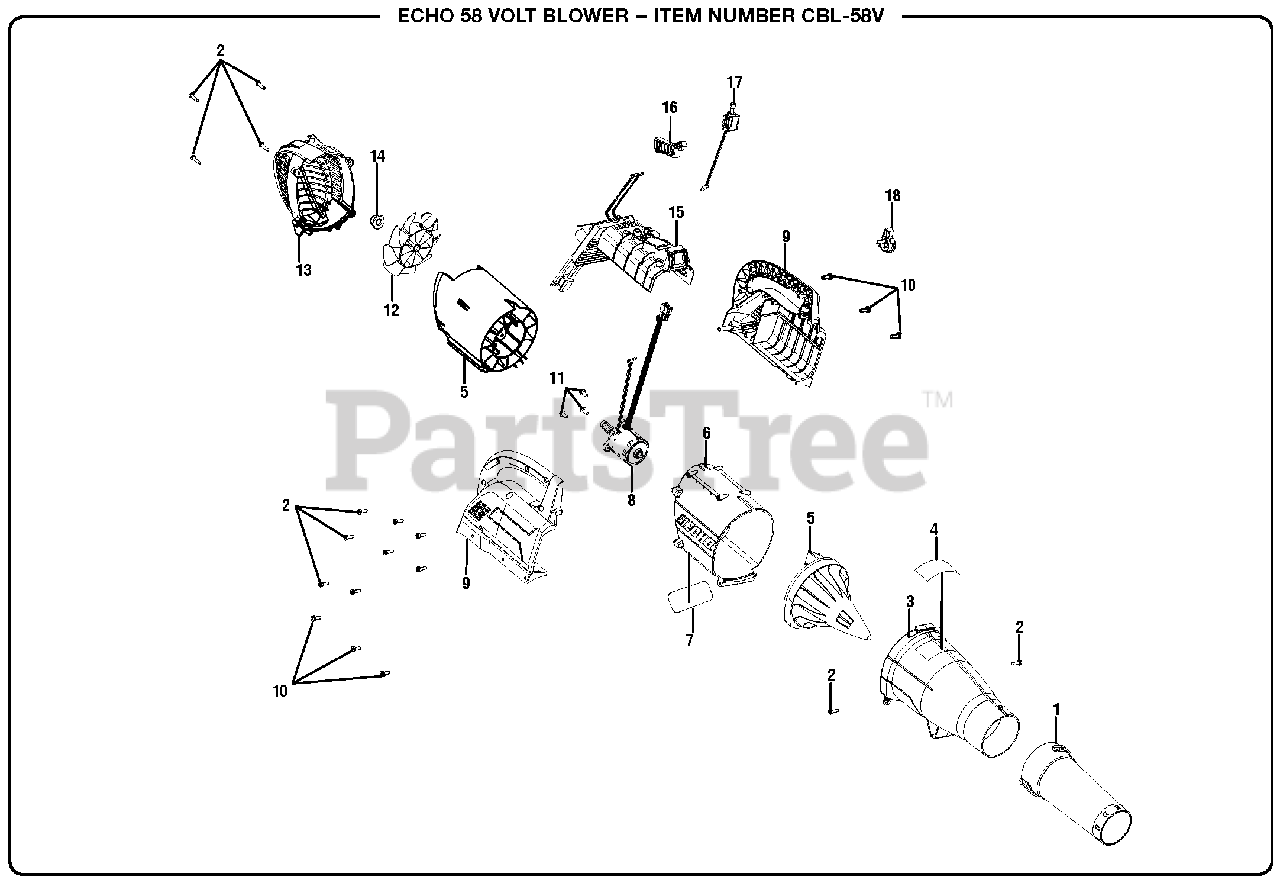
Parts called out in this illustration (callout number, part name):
1	Nozzle and Scraper Assembly
2	Screw (M5, T25 Torx)
3	Outlet Housing
4	Warning Icon Label
5	Tailcone and Guide Vein Assembly
6	Motor Housing Assembly
7	Data Label
8	Motor Assembly
9	Housing Assembly
10	Screw (M5 x 15 mm, T25 Torx)
11	Screw (M5 x 8 mm, T25 Torx)
12	Fan w/Insert
13	Guard Inlet
14	Lock Nut (M8 x 1.25)
15	Circuit Board & Battery Carriage Assembly
16	Trigger Button
17	Variable Speed Switch
18	Speed Adjustment Knob Assembly
